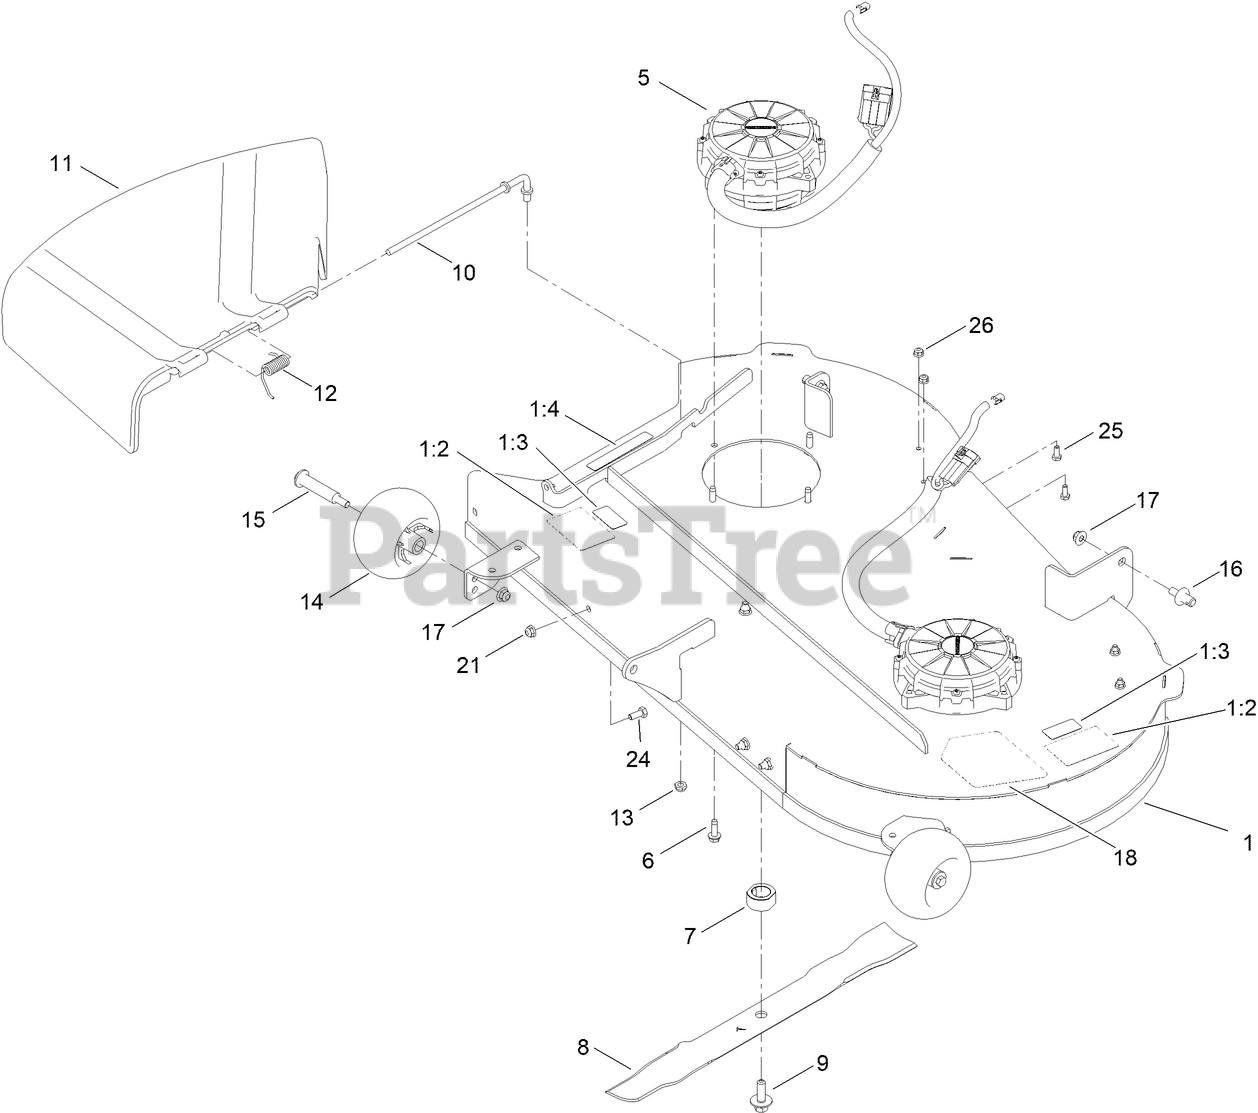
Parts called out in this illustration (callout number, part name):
1	42 IN DECK AND DECAL ASM
1:2	DECAL-DANGER, DECK
1:3	DECAL-NO SPRAY
1:4	DECAL-DANGER
5	MOTOR-DECK
6	SCREW-THD ROLL, HWH
7	DRIVER-BLADE
9	BOLT-BLADE, SEMS
10	ROD-PIVOT
11	DEFLECTOR-DISCHARGE
12	SPRING-TORSION
13	NUT-HEX
14	ROLLER-SCALP, ANTI
15	BOLT-SHOULDER
16	PIN-DECK
17	NUT-HF, NI
18	DECAL-IRON FORGED, 42
21	NUT-HF
24	SCREW-HH
25	SCREW-HH
26	NUT-FLANGE, NI
